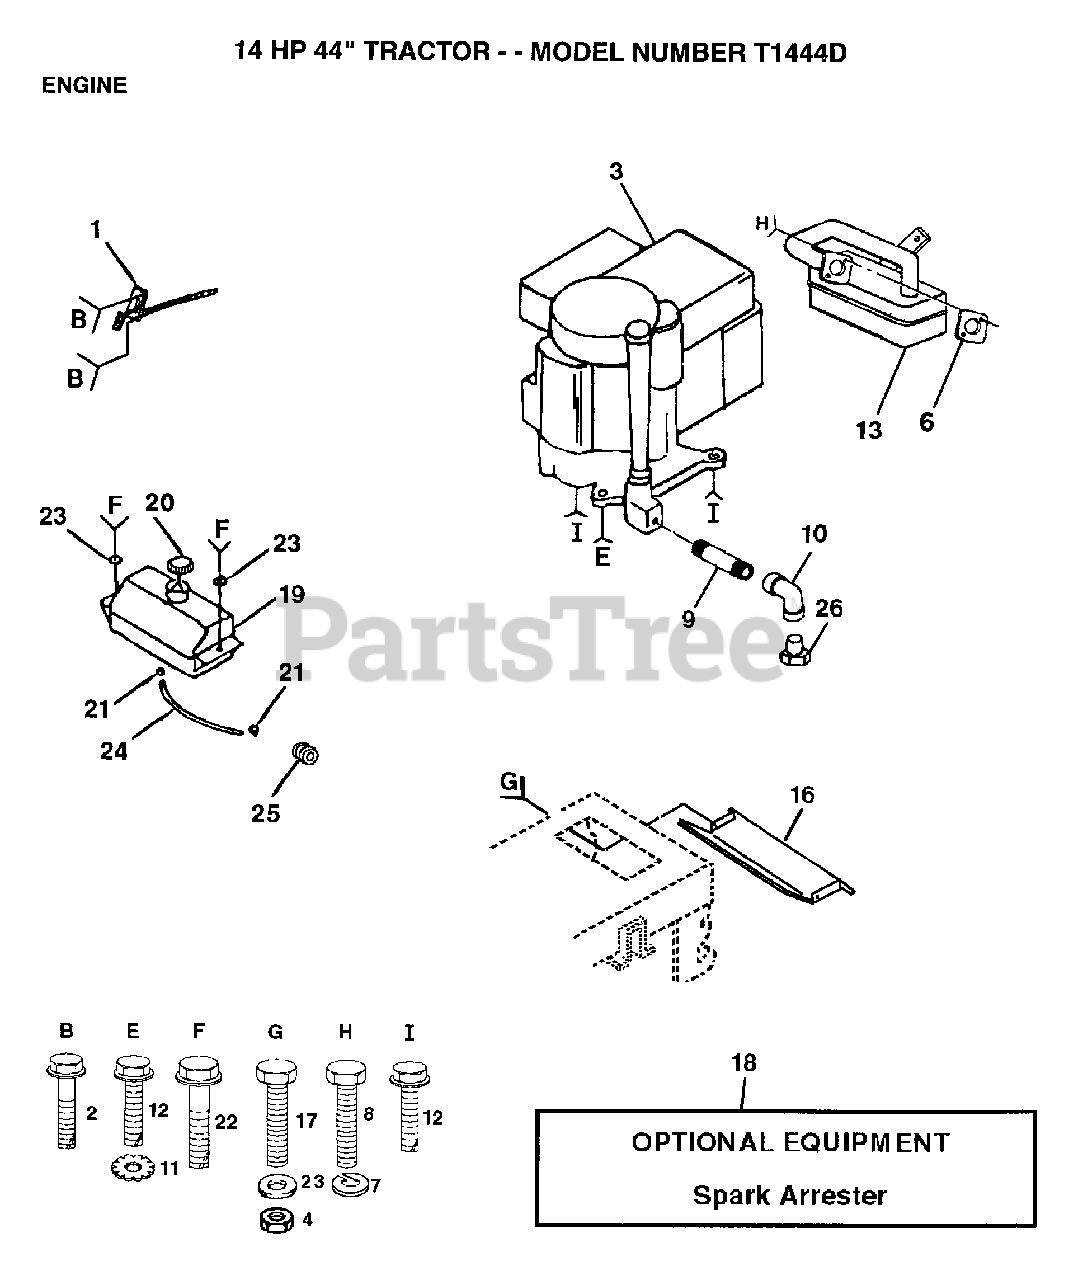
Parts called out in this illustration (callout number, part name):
2	SCREW LT
4	"NUT,SELF RETAININ"
7	LOCKWASHER
8	SCREW LT
9	PIPE NIPPLE
10	ELBOW
11	LOCKWASHER
12	SCREW
13	MUFFLER
17	BOLT LT
19	TANK.FUEL.LT.
21	HOSE CLAMP
22	SCREW HEX CRT
23	WASHER
